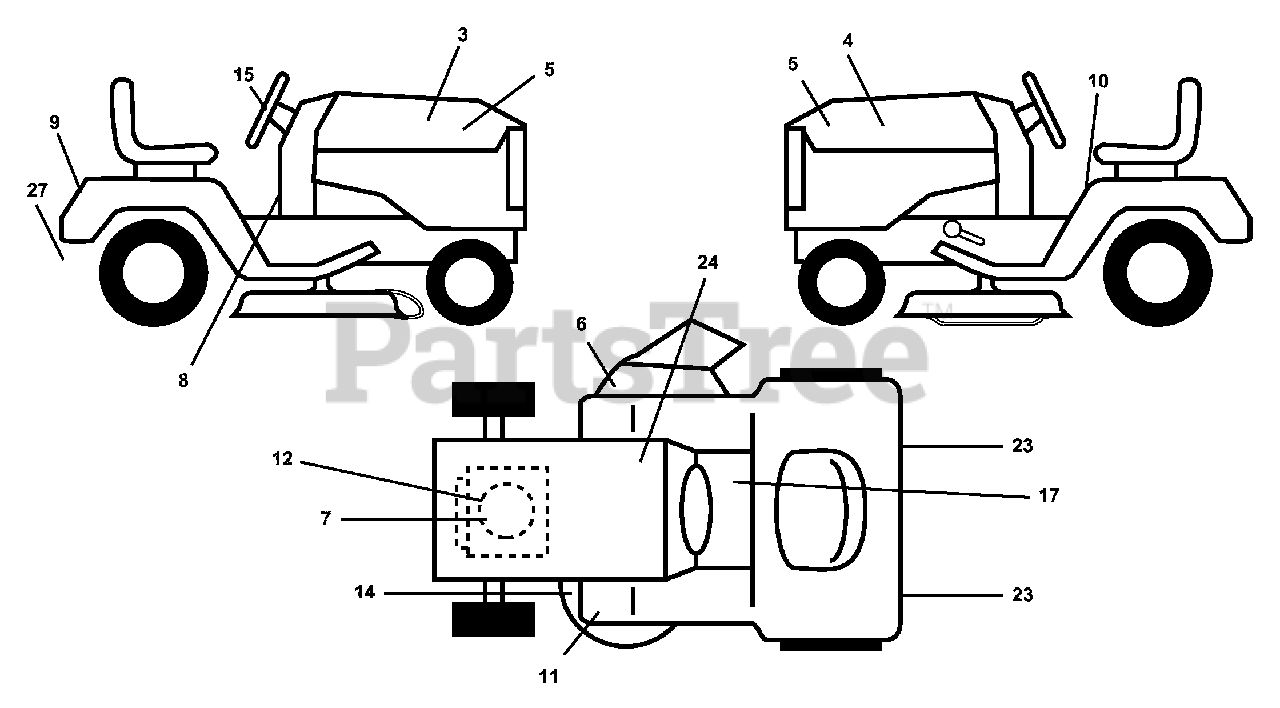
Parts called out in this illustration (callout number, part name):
3	Decal, Hood, RH
4	Decal, Hood, LH
5	Decal, Side Panel
6	Decal, Warning
7	Decal, Engine HP
8	Decal, Dash
9	Decal, Fender
10	Decal, Danger
11	Decal, Clutch/Brake
12	Decal, Engine RCL
14	Decal, V-Belt Schematic
15	Decal, Ins. Strg Whl
17	Decal, Saddle Brake Parking
23	Reflector, Taillight
24	Decal, Btry Dngr/Psn
27	Decal, Drawbar
